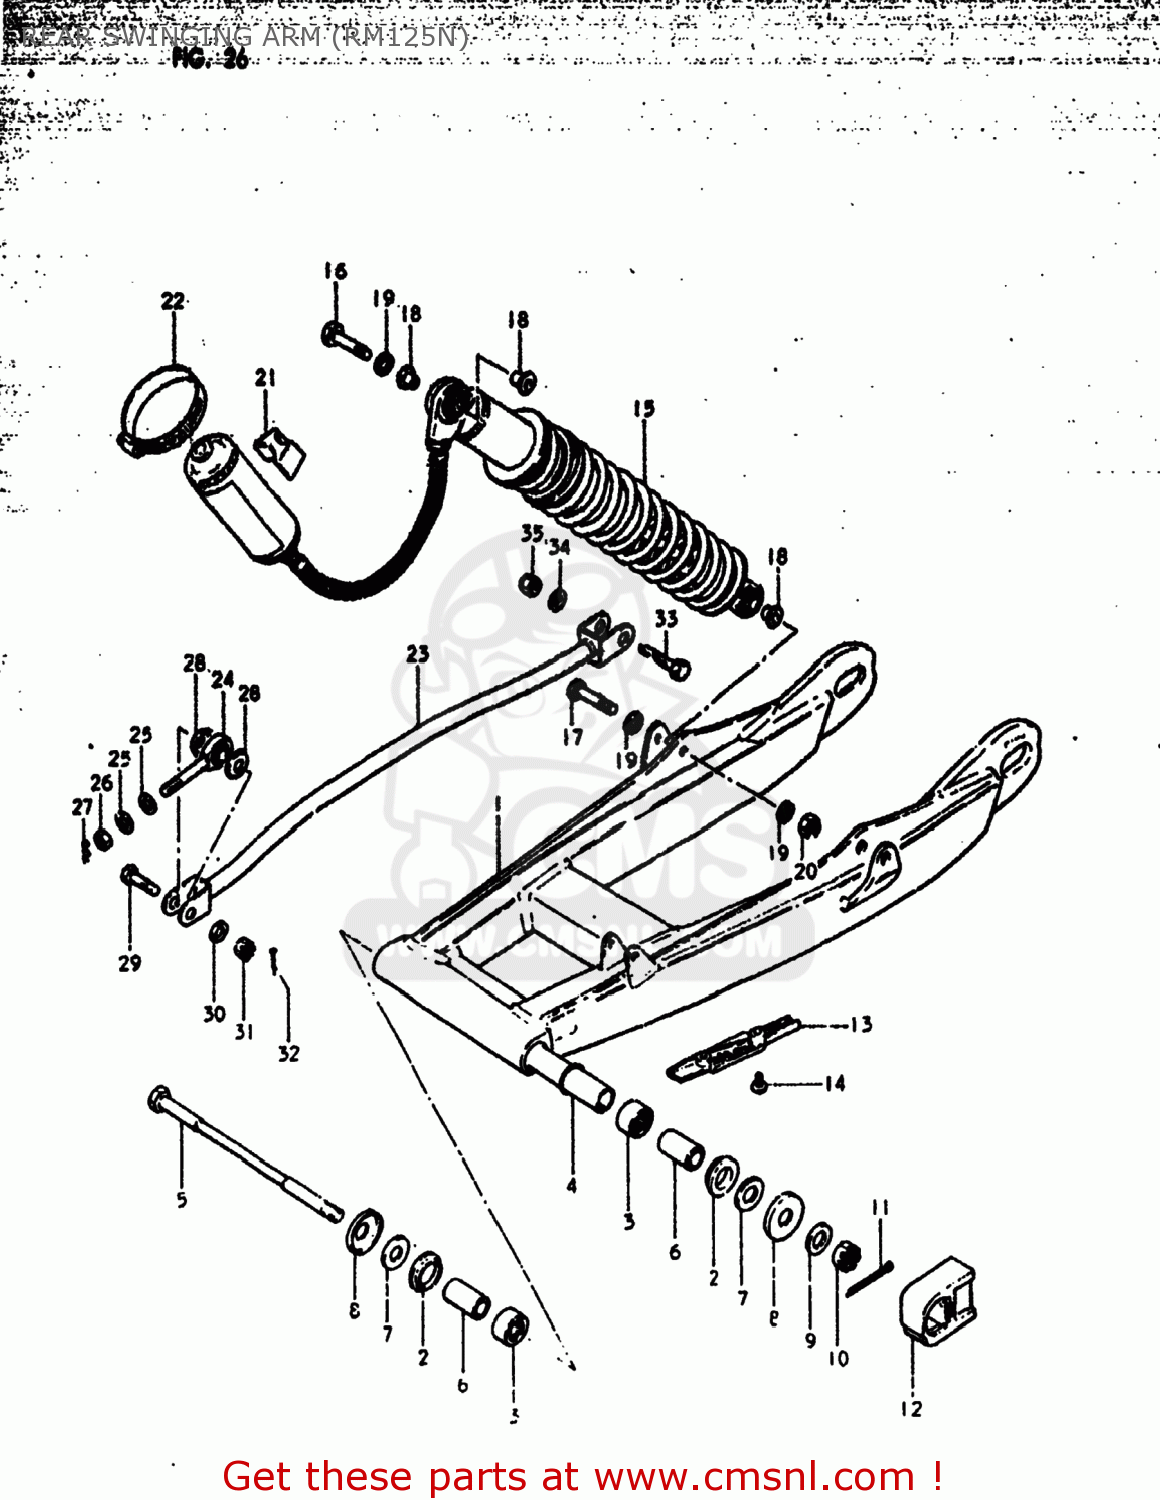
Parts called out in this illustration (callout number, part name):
1	SWING ARM ASSEMBLY,REAR
2	BUSH,RR SWINGINGARM PIVOT
3	ROLLER BEARING (17X24X2
4	SPACER,SWING ARM,CENTER
5	SHAFT,REAR SWING ARM
6	SPACER,RR SWGARM PIVOT
7	WASHER
8	COVER,REAR SWING ARM DUST
9	WASHER
10	NUT, REAR AXLE
11	COTTER PIN
12	BUFFER,CHAIN TOUCH DEFLECTOR
13	BUFFER,CHAIN TOUCH DEFLECTOR
14	SCREW
15	ABSORBER ASSEMBLY,REAR SHOCK
16	BOLT
17	BOLT(8X46)
18	SPACER,RR SHK ABS INNER
19	WASHER
20	NUT
21	CUSHION,RR SHOCK ABSORBER
22	CLAMP
23	TORQUE LINK,REAR
24	BEARING
25	WASHER
26	NUT
27	PIN
28	DUST SEAL,TORQUE LINK FR BRG
30	WASHER
31	NUT 8MM
32	PIN 20X20
33	BOLT 10X40
34	WASHER
35	NUT
